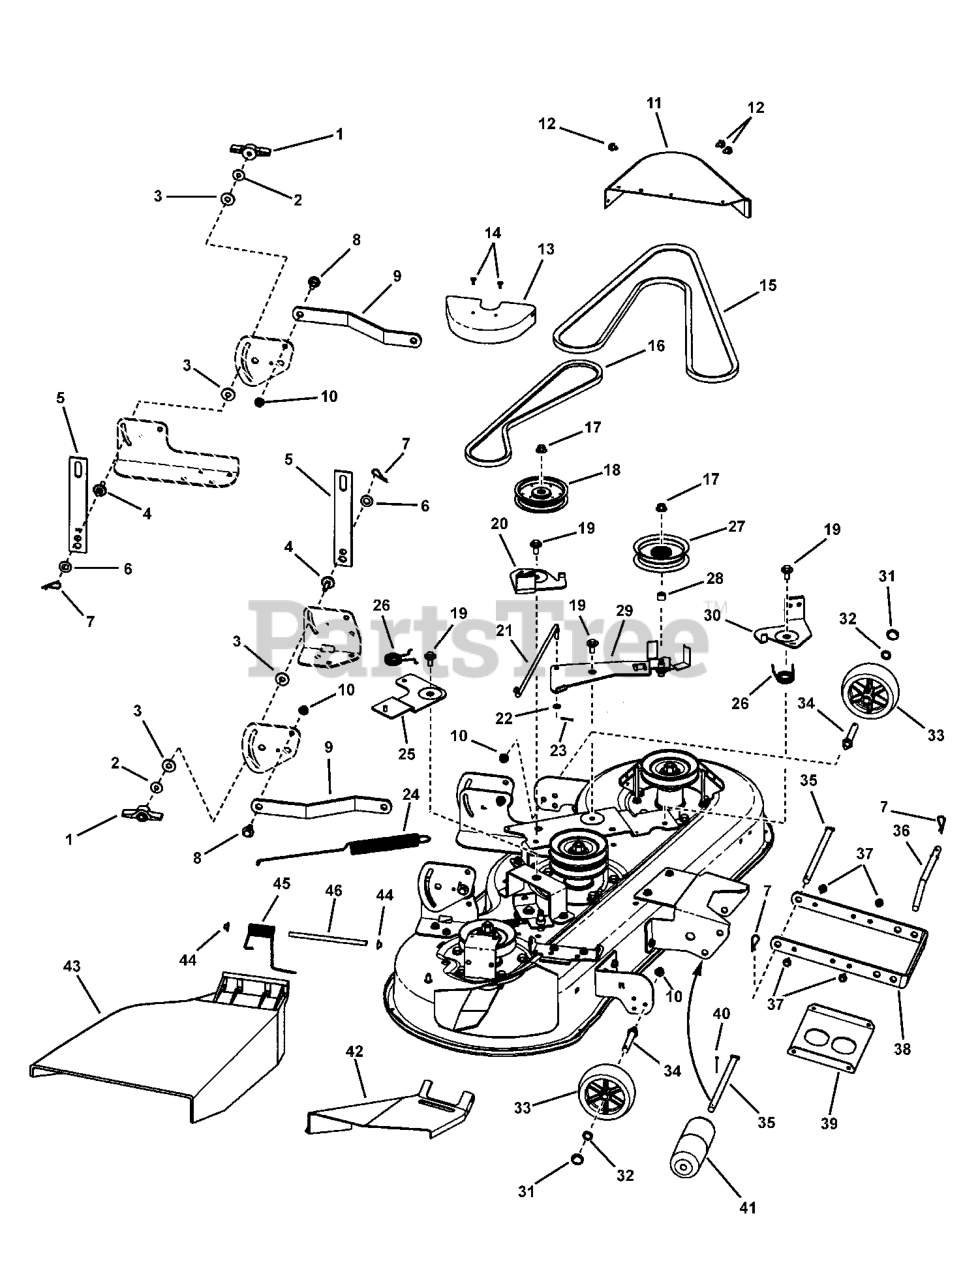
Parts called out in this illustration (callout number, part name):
1	KNOB, (5/16-18 thread)
2	WASHER, FLAT, 1.0 X .328 X 16GA
3	FRICTION PAD
4	PIN - HANGER 3/8-16 X 1.25
5	LINK, LIFT
6	WASHER, FLAT, 1.0"OD X 0.550"
7	HAIR PIN, .56D-.092T
8	SHOULDER BOLT, 3/8-16 X .600OD X.95L
9	BRACKET, REAR SUSPENSION
10	NUT, HEX FLANGE, 3/8-16 NC
11	COVER, LEFT PULLEY
13	COVER, RIGHT PULLEY
14	SCREW, THREAD FORMING 10-24X.340MIN THREADS
15	BELT, PRIMARY 46" (HA, 86.91" E.L.)
16	BELT, SECONDARY, 46" (HA, 47.10" E.L.)
17	NUT FLANGE, 3/8-16 ZINC PLATED
18	PULLEY, Idler, (4.0 OD, straight edges) R.H. side
19	SHOULDER BOLT, 0.75 X 0.60 X 3/8-16
20	BRAKE ASSEMBLY CENTER
21	LINK BELLCRANK
22	FW, .34X.62X16GA
23	PIN - COTTER, 0.75 X 0.090
26	SPRING, TORSION BRAKE
27	PULLEY, Idler, (4.0 OD, flared edges) L.H. side
28	SPACER, 1/2" TO 17MM
29	ASSY - IDLER ARM, 46"
30	ASSY - BRAKE LH 46"
31	CLIP - HAIR PIN
32	WASHER, FLAT, .81 X .550 X 16GA
33	WHEEL GAGE
34	BOLT, Gauge Wheel
35	ROD, DECK SUSPENSION
36	ROD, HANGER
37	CAPSCREW 5/16-18
38	BRACKET, FRONT SUSPENSION
39	STIFFENER
40	COTTER PIN
42	DEFLECTOR, INSIDE
43	DEFLECTOR, CHUTE
44	CAP, PUSH ON
45	SPRING - TORSION
46	ROD, DEFLECTOR
